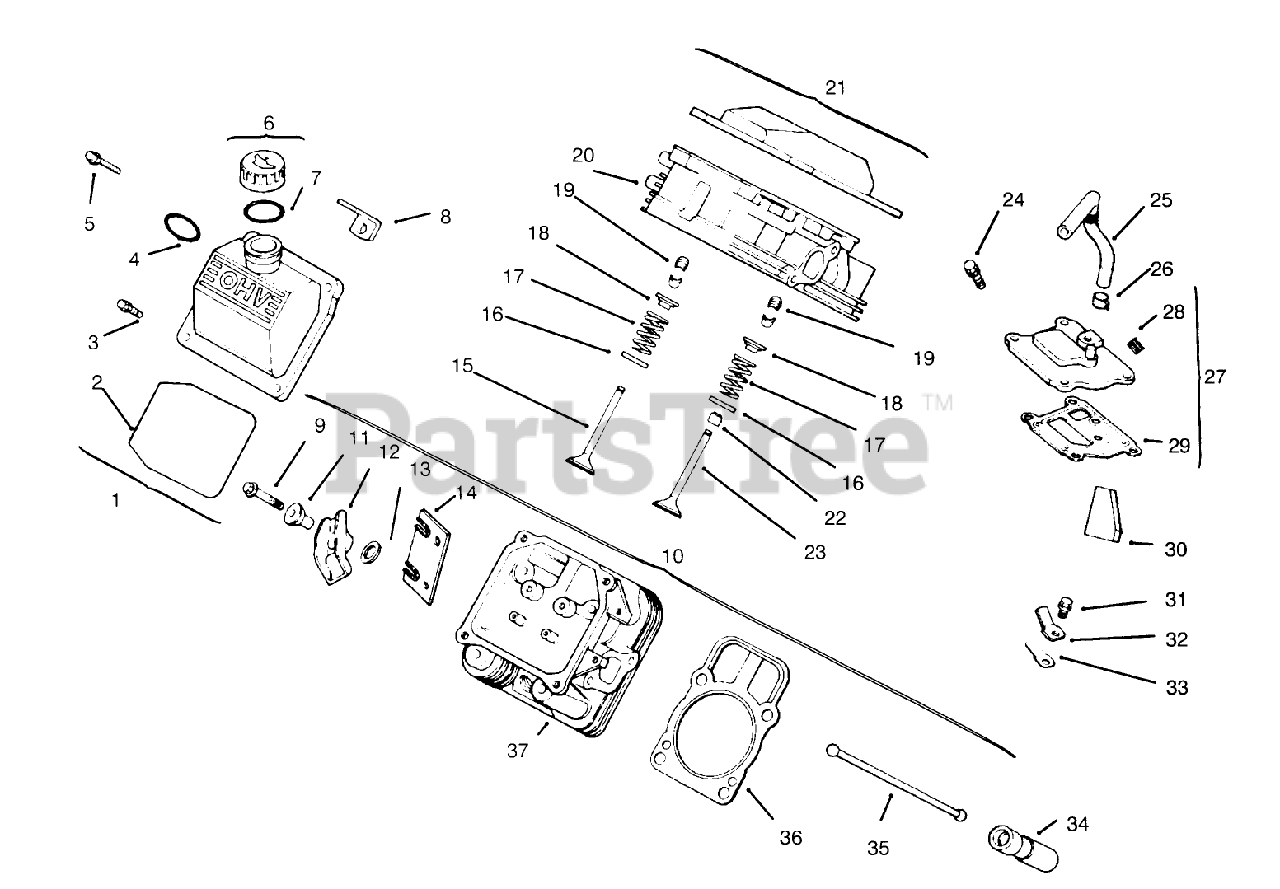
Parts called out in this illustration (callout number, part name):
1	Kit-Valve Cover (Incl. Ref. #2-4)
2	O Ring
3	Screw
4	O-Ring
5	Screw
6	Kit-Oil Fill Cap (Incl. Ref. #7)
7	"O"Ring
8	Strap-Lifting
10	Kit-Valve Train (Incl. Ref. #11-14 & 35)
11	Pivot-Rocker Arm
12	Arm-Rocker
13	Washer
14	Plate-Guide
15	Valve-Exhaust
16	Retainer-Spring
17	Spring-Valve
18	Cap-Spring, Valve
19	Retainer Kit
20	Head Asm-#1 Cylinder
21	Kit-Valve Cover (Incl. Ref. #2 & 3)
22	Seal-Stem, Valve
23	Valve-Intake
24	Screw
25	Hose-Breather
26	Clamp
27	Kit-Breather w/Plug (Incl. Ref. #28 & 29)
28	Plug
29	Gasket-Breather
30	Filter-Breather
31	Screw
32	Retainer-Reed
33	Reed
34	Lifter-Valve
35	Rod-Push
36	Gasket-Cylinder Head
37	Head Asm-#2 cylinder
